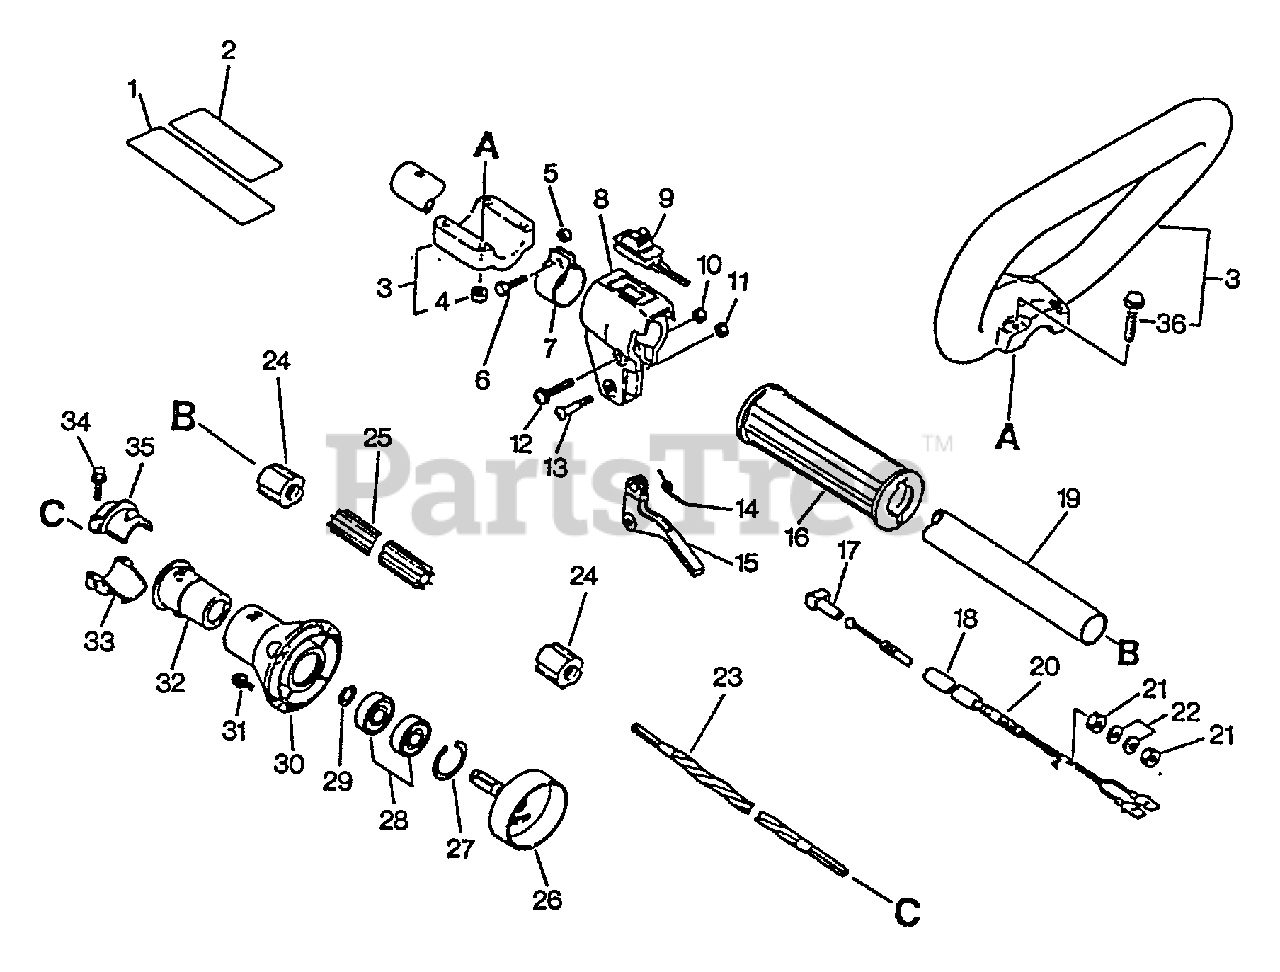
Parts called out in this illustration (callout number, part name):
1	LABEL - CAUTION
2	LABEL, CAUTION
3	LOOP HANDLE ASSY
4	NUT M5
5	SPACER, GUARD
6	BOLT 5×18
8	BRACKET, THROTTLE CONTROL
9	SWITCH, ON-OFF
10	NUT M5
11	NUT, LOCK M5
12	SCREW 5×30
14	SPRING, THROTTLE
15	TRIGGER, THROTTLE
16	GRIP
17	GUIDE, CABLE
19	MAIN PIPE ASSY 25×1500
20	CABLE, THROTTLE
22	WASHER 6.5×11.5×0.8
23	DRIVESHAFT - FLEXIBLE L= 1522
25	LINER, FLEXIBLE 21.6×1420
26	DRUM, CLUTCH
27	RING, SNAP 28
28	BEARING, BALL 6001
29	RING, RETAINING - 12
30	CASE, CLUTCH - GRAY
31	SCREW 5×16
34	BOLT - 5×25
35	HOLDER, MAIN PIPE - UPPER
36	SCREW 5×35
